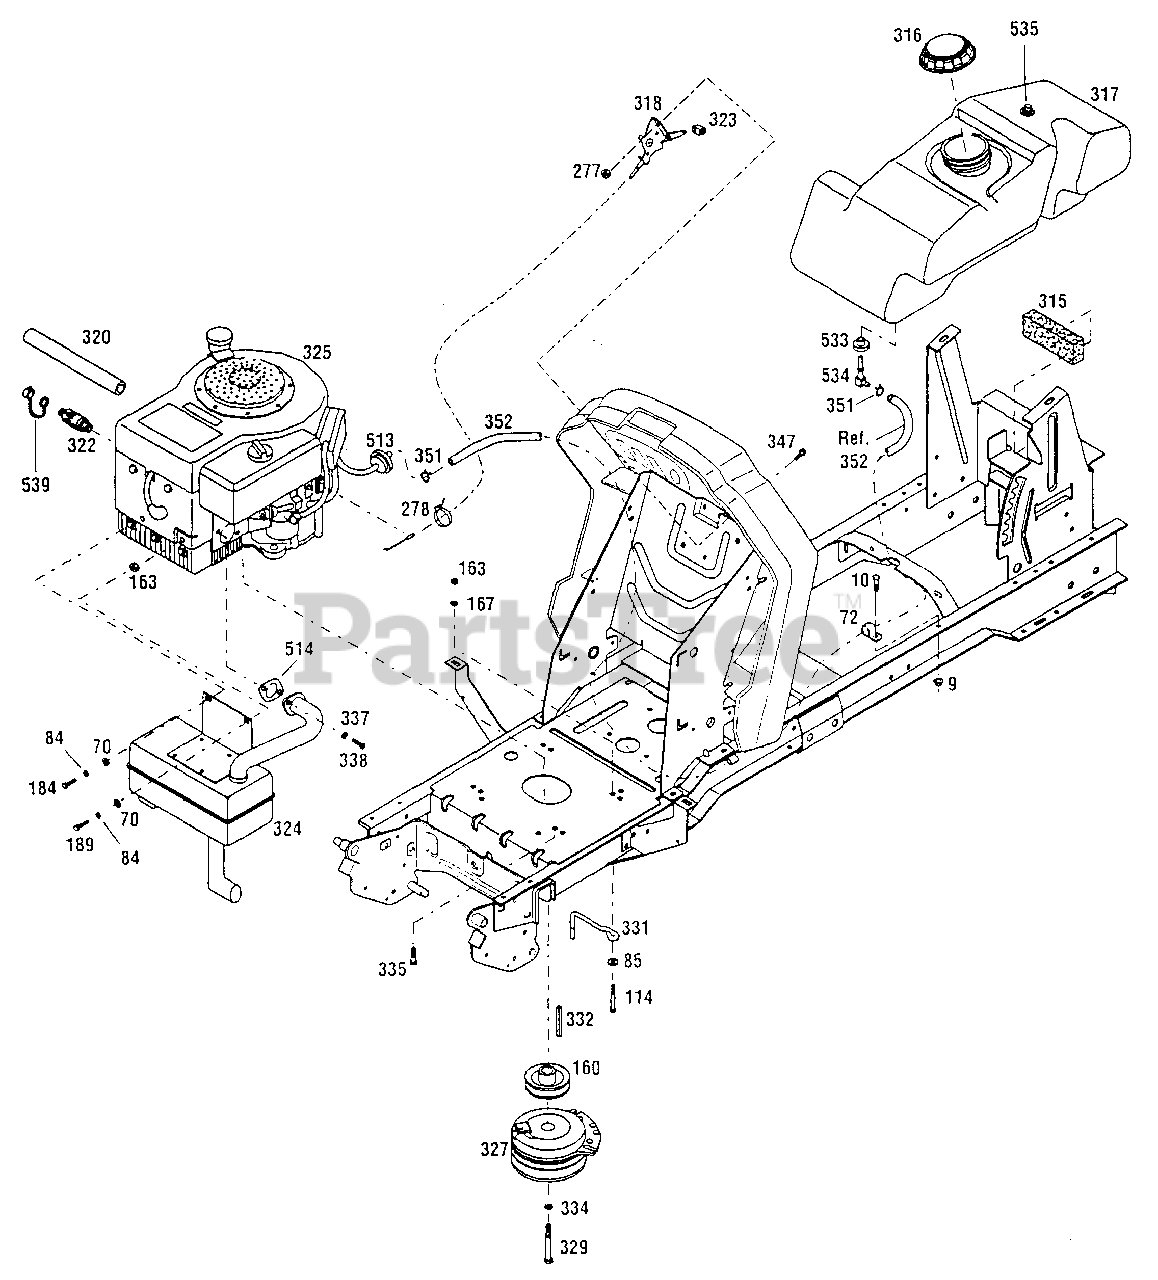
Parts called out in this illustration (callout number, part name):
9	Flange Nut, 5/16-18
10	Hex Head Screw, 5/16-18 x 3/4
70	Flat Washer, 1/4
84	Lock Washer, 1/4 SAE
85	Flat Washer, 3/8
114	Hex Head Screw, 3/8-16 x 1-1/2
160	Engine Sheave
163	Nut, 3/8-16
167	Lock Washer, 3/8
184	Hex Head Screw, 1/4-20 x 7/8
189	Hex Head Screw, 1/4-20 x 1-1/4
277	Keps Nut, 10-24
278	Cable Tie
315	Fuel Tank Pad
316	Fuel Cap
317	Fuel Tank (Incl. Refs. 533, 534 & 535)
318	Throttle Control
320	Oil Drain Hose
322	Oil Valve Assembly (Incl. Ref. 539)
323	Control Knob
324	Muffler
325	Engine, 13 HP (engine part)
327	Electric Clutch
328	Special Washer
329	Hex Head Cap screw, 7/16-20 x 3
331	Clutch Retainer
332	Square Key, 1/4 x 1-1/2
334	Spring Lock Washer, 7/16
335	Screw, 3/8-16 x 1
337	Special Lock Washer, 5/16
338	Screw, 5/16-18 x 3/4
347	Machine Screw, 10-24 x 3/4
351	Hose Clamp
352	Fuel Line
513	Fuel Filter
514	Muffler Gasket
533	Bushing
534	Fuel Tank Elbow
535	Fuel Tank Vent
539	Oil Drain Cap
